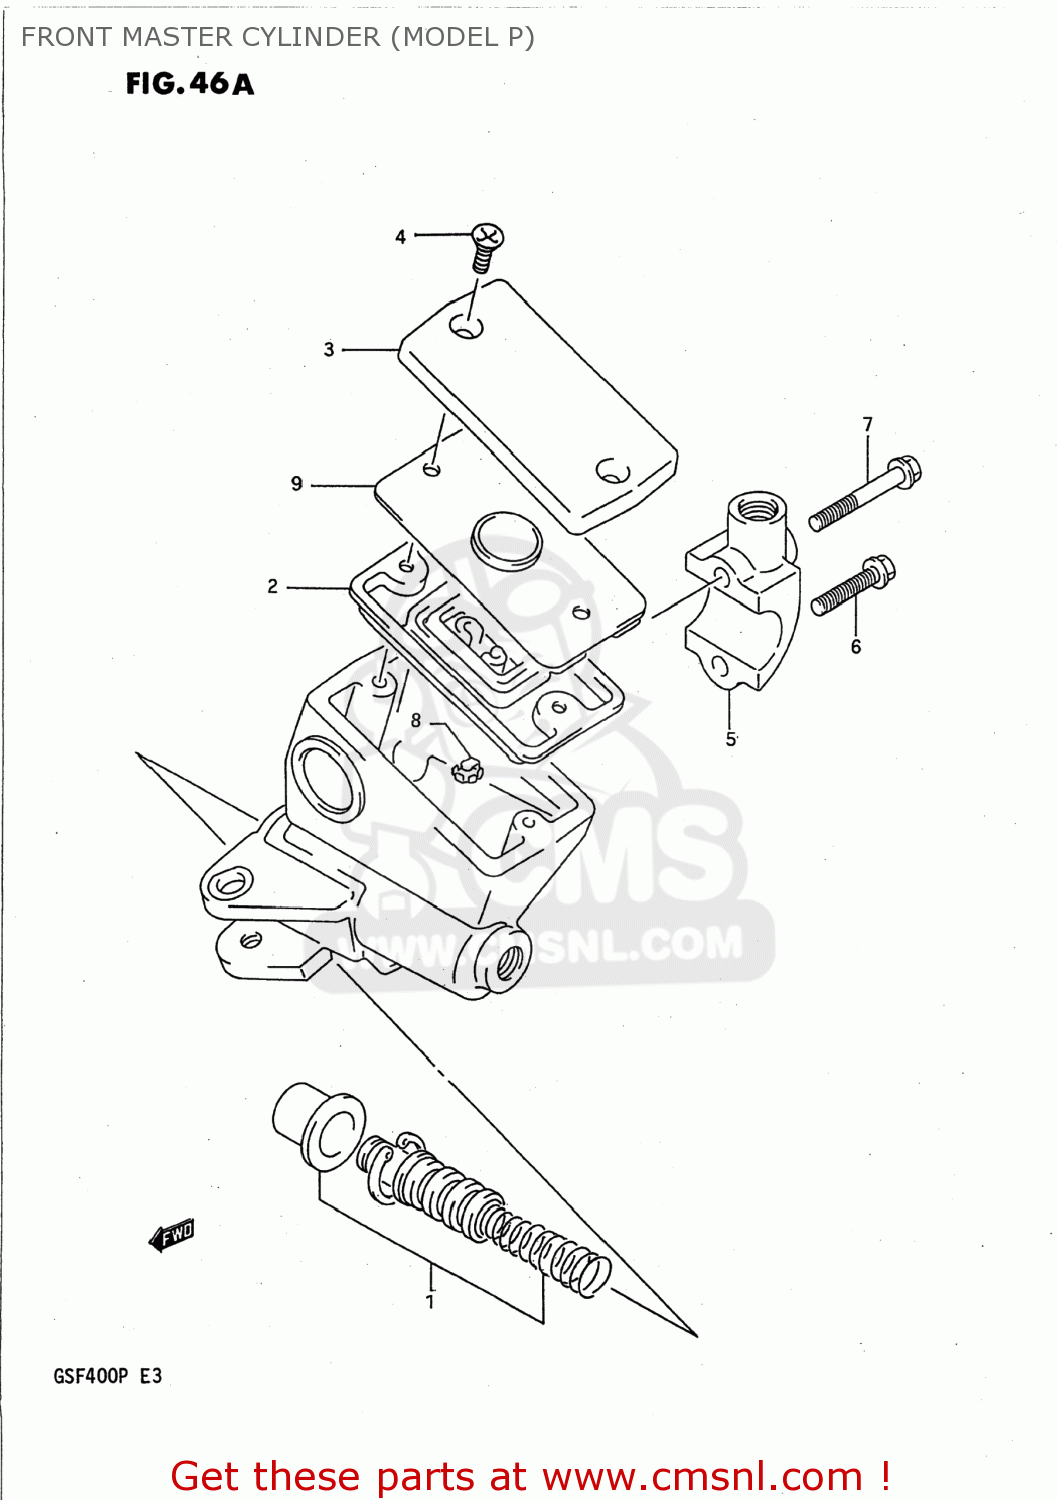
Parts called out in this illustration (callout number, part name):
1	CUP SET,MASTER CYLINDER
2	3
3	CAP
4	SCREW
5	HOLDER
6	BOLT(6X25)
7	BOLT(6X38)
8	PROTECTOR
9	PLATE,DIAPHRAGM
